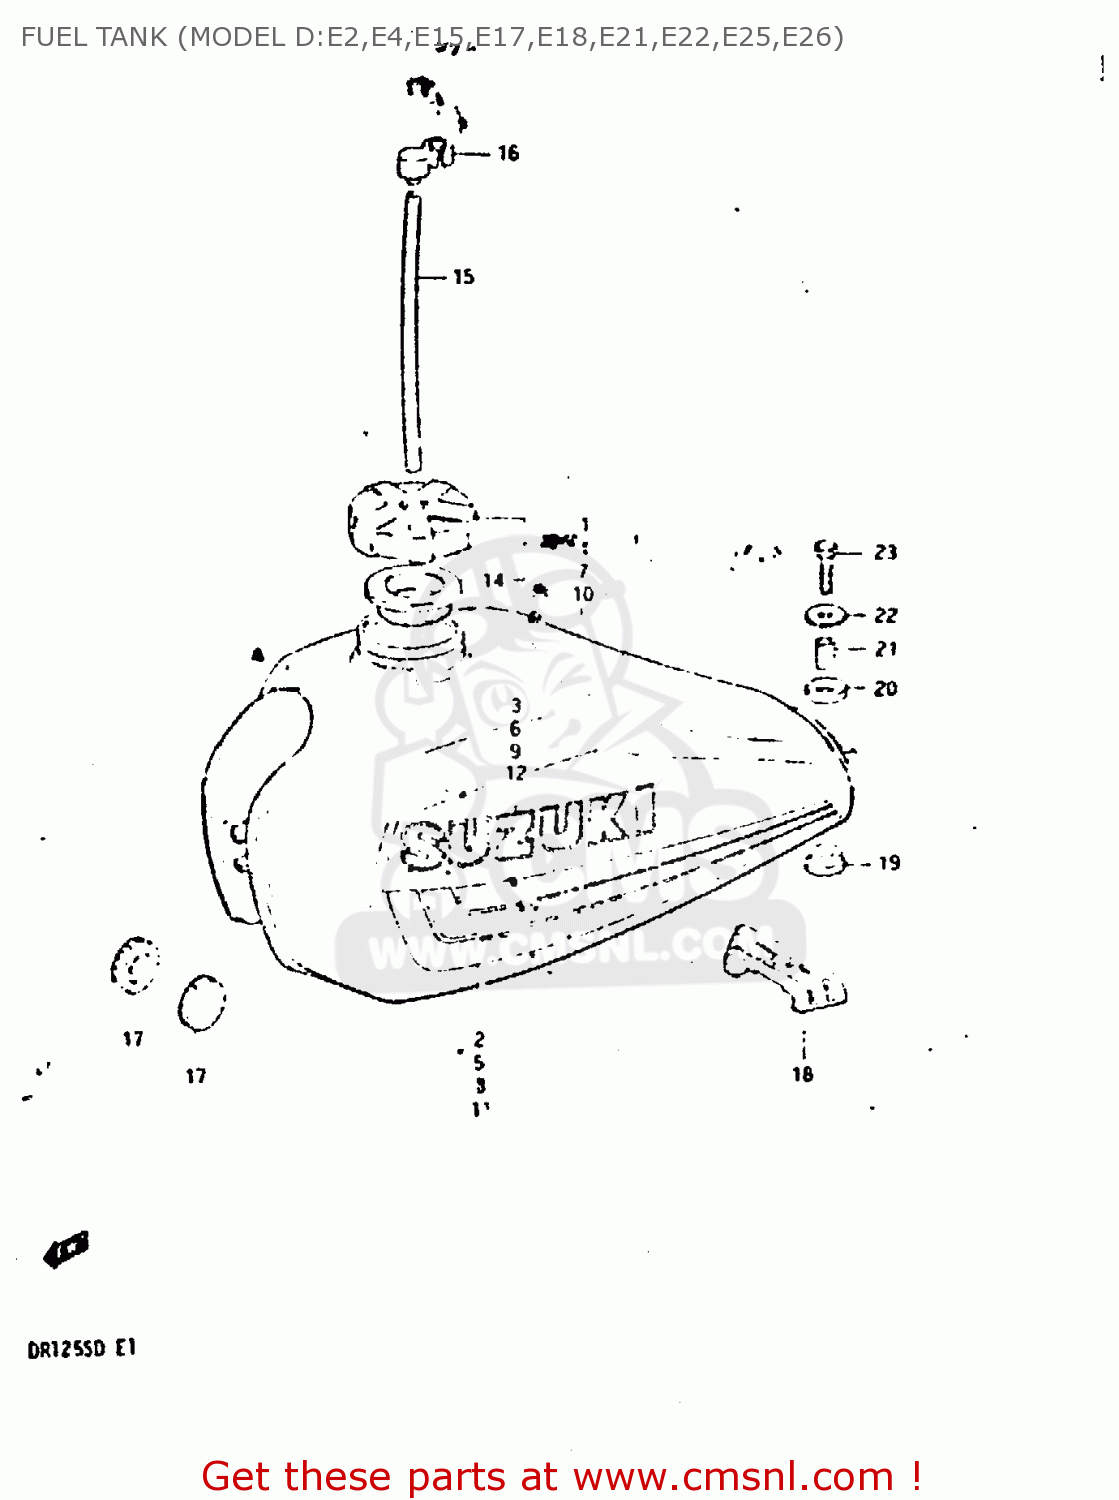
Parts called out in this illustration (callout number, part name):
1	TANK ASSY, FUEL (BLACK)
2	TAPE SET, FUEL TANK
3	EMBLEM,FUEL TANK(WHITE)
4	TANK ASSY, FUEL (BLUE)
5	TAPE SET, FUEL TANK
6	EMBLEM,FUEL TANK(WHITE)
7	TANK ASSY, FUEL (RED)
8	TAPE SET, FUEL TANK
9	EMBLEM,FUEL TANK(WHITE)
10	TANK ASSEMBLY,FUEL
11	TAPE SET,FUEL TANK
12	EMBLEM
13	CAP SET,FUEL TANK
14	GASKET (NAS)
15	HOSE
16	CLAMP,FUEL TANK BREATHER HOSE
17	CUSHION
18	CUSHION,FUEL TANK
19	CUSHION
20	CUSHION
21	SPACER(8.5X12X19)
22	WASHER (8.5X29X1.6)
23	BOLT (8X30)
